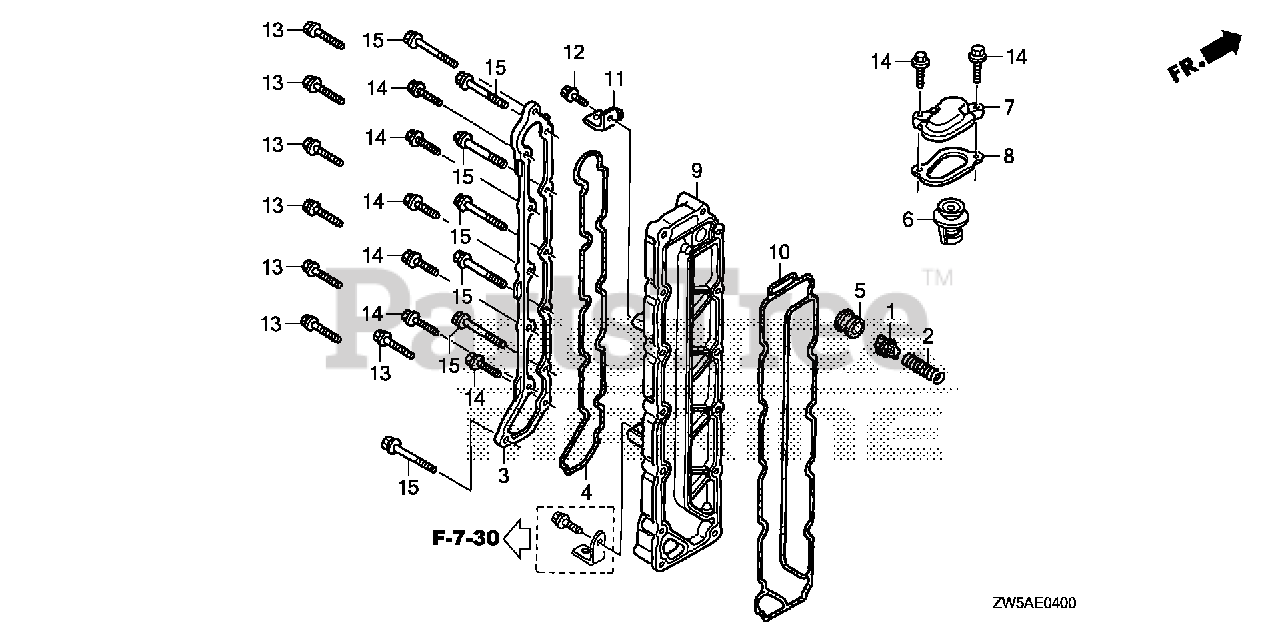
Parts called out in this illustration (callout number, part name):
1	VALVE, RELIEF
2	SPRING, RELIEF VALVE
3	COVER, RELIEF VALVE
4	GASKET, RELIEF VALVE COVER
5	GASKET, RELIEF VALVE
6	THERMOSTAT ASSY.
7	COVER, THERMOSTAT
7	COVER, THERMOSTAT *NH8* (DARK GRAY)
8	GASKET, THERMOSTAT COVER
9	COVER, WATER JACKET *NH8* (DARK GRAY)
10	GASKET, WATER JACKET COVER
11	STAY A, IGNITION WIRE CLAMP
12	BOLT, FLANGE (6X12) (CT200)
13	BOLT, FLANGE (6X25)
14	BOLT, FLANGE (6X20)
15	BOLT, FLANGE (6X45)
